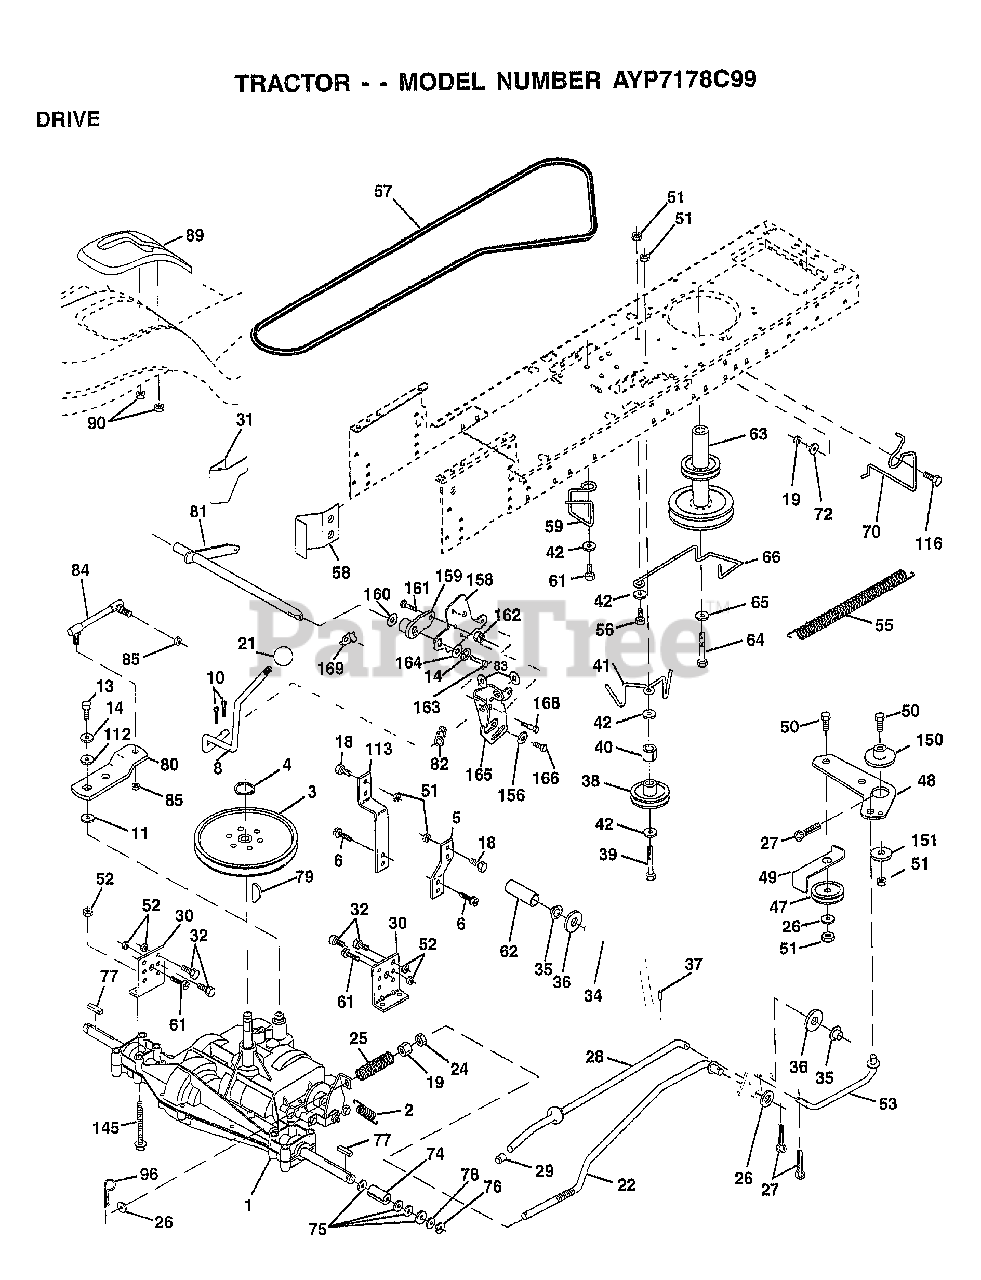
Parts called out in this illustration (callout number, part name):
2	SPRING.BRAKE.RETU
3	PULLEY TRANS
5	STRAP TORQUE
6	SCREW
8	RODL.SHIFT.FEND.ADJ.STLT
10	PIN COTTER 1/8
11	WASH-SHFT PLT LT
13	BOLT.1/4-28.W/PAT
14	LOCKWASHER
18	BOLT
19	NUT
21	KNOB T (1/2-HOLE)
22	BRAKE ROD
24	NUT
25	SPRING ROD LT
26	WASHER
27	COTTER PIN
28	ROD.BRAKE.PARK.LT
30	TRANSAXLE MTG BKT
31	"KEEPER,BELT LH T"
32	BOLT
34	SHAFT ASM-PEDAL F
35	NYLON BEARING
36	WASHER LT
38	FLAT IDLER PULLEY
39	BOLT
40	SPACER T
41	"KEEPER,BELT.IDLER FLAT"
42	WASHER
48	BELLCRANK.CLUTCH
49	RETAIN BELT
53	"LINK, CLUTCH T"
55	"SPRING, RETURN LT"
58	"KEEPER,BELT RH T"
59	KEEPER BELT CNTSP
61	SCREW
62	PEDAL COVER T
63	PULLEY.ENGINE
64	BOLT
65	LOCKWASHER
66	KEEPER-BELT
70	KEEPER BELT ENG
72	WASHER
74	SPACER AXLE
75	WASHER
76	E-RING LT
77	SQUARE KEY
78	WASHER
80	"ARM.SHIFT.20""TIRE"
81	SHAFT.ASM.CROSS
82	SPRING.SHIFT.STLT.GREY
83	WASHER
84	LINK.TRANSAXLE.PMST/DANA
85	NUT.CNT.LOCK.1/4
89	CONSOLE.SHIFT.STLT.6SP.BLACK
90	NUT
96	RETAINER M
112	WASHER LT
113	"STRAP,TORQUE"
116	BOLT RDHD 3/8-16
145	BOLT.HEX.FLGHD
150	BUSHING.BELLCRANK.GRD.DR
151	WASHER
156	WASHER.SRRTD.5/16
158	BRKT.SHIFT.MOUNT
159	HUB.SHIFT
160	WASHER
161	BOLT T
164	WASHER.5/8X.281X10GA
165	BRKT.PIVOT.LEVER
166	SCREW.5/16-18X5/8
168	BOLT.SHOULDER.5/16-18X.561
169	PLATE.FASTENING
